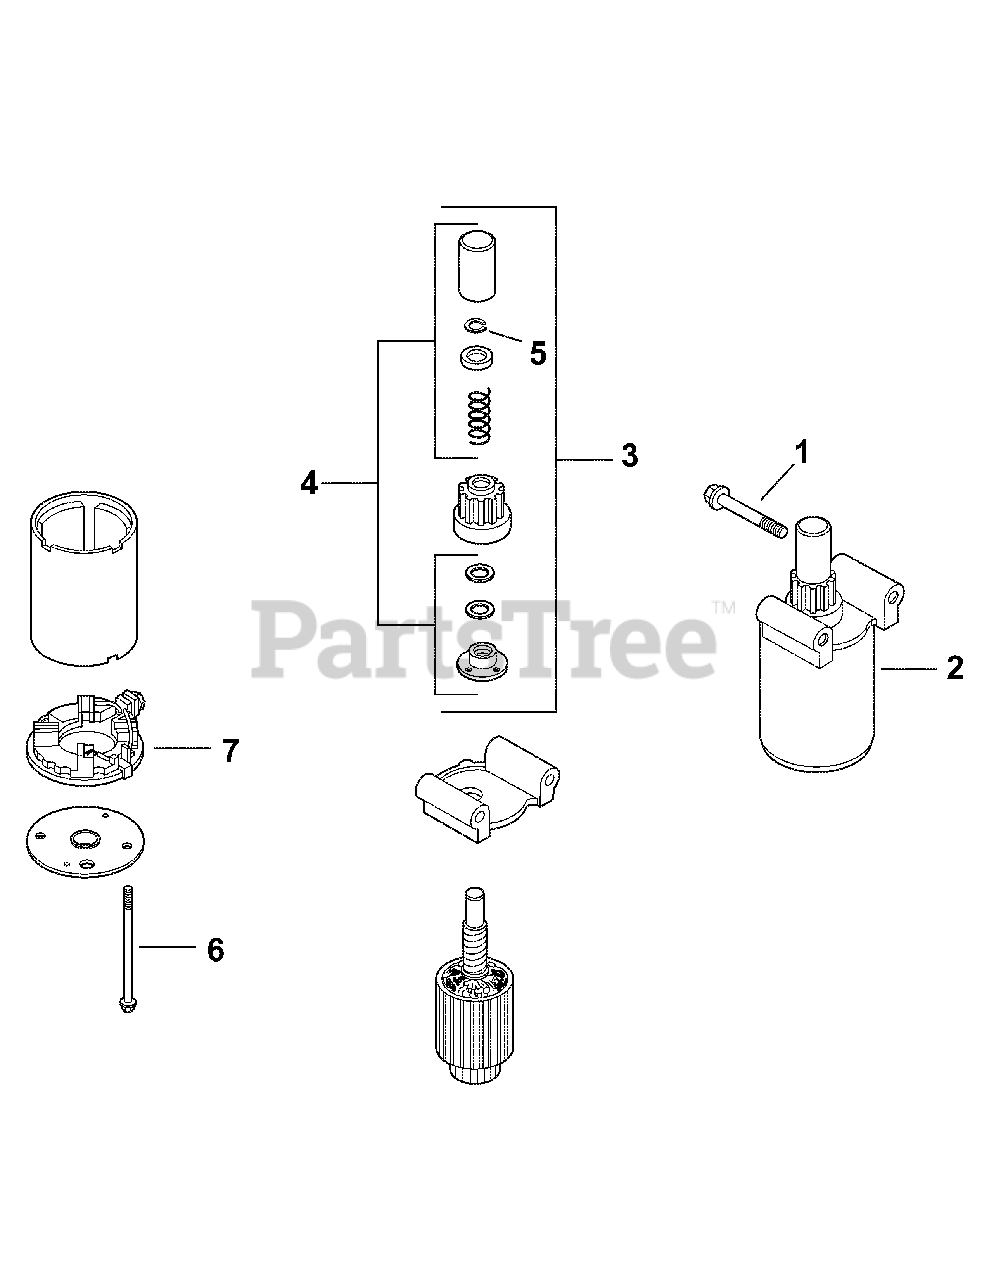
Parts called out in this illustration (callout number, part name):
1	Screw, hex. flange M8x1.25x70
2	Starter assembly (Includes 3-5)
4	Kit, drive parts
5	Ring, Retaining
7	Commutator, end cap
